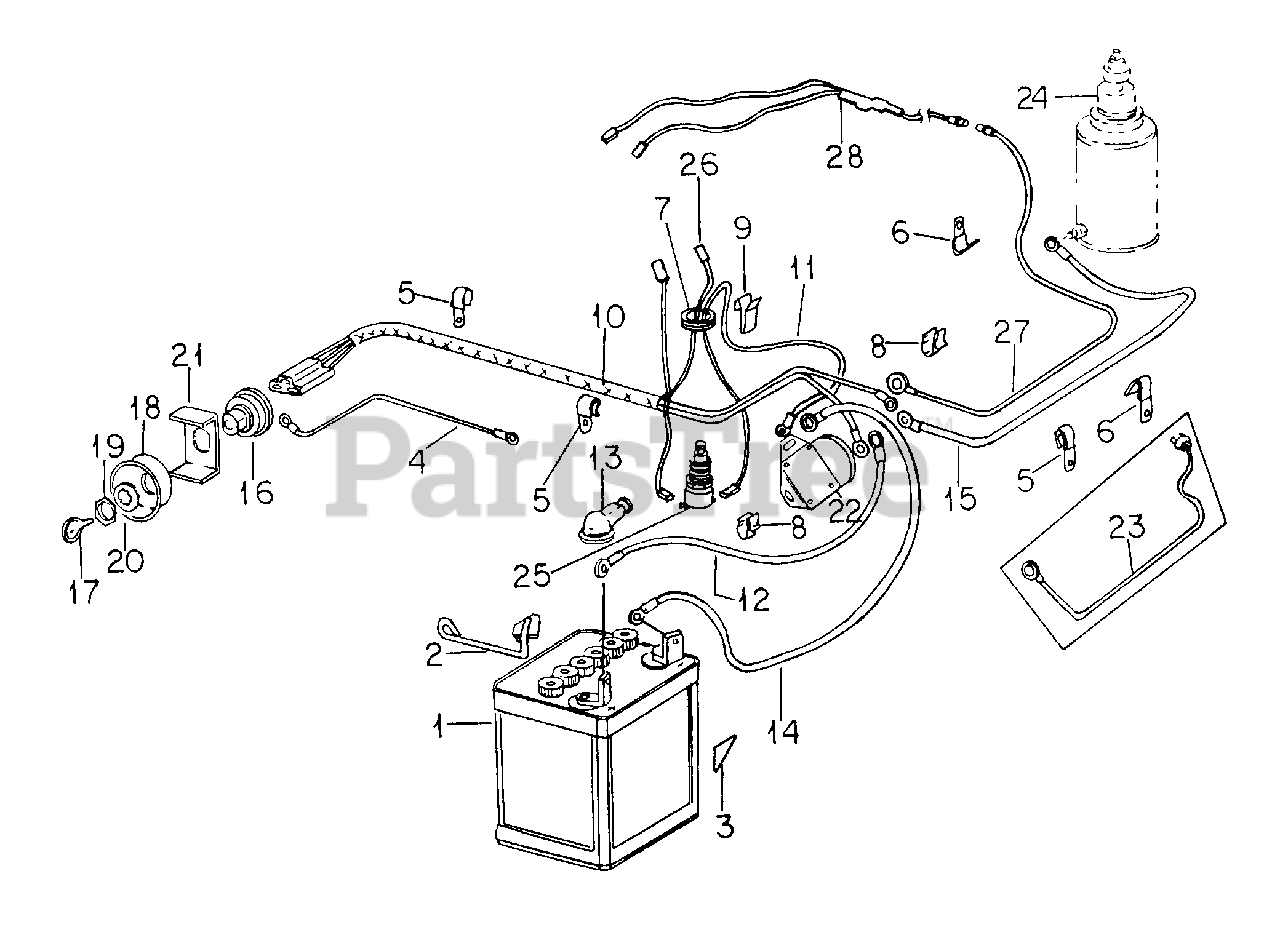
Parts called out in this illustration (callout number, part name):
1	BATTERY, LOW-MAINTENANCE -12 VOLT-
2	CLAMP ASSY, BATTERY
3	PAD, BATTERY
4	CABLE ASSY, SWITCH TO GROUND
6	CLIP, CABLE
8	CLIP. SPEED
9	CLIP, CABLE SPEED
10	HARNESS, CABLE
11	CABLE, PTO SWITCH TD MAGNETIC SWITCH
12	CABLE, BATTERY POSITIVE
13	INSULATOR, BATTERY CABLE
14	CABLE, BATTERY GROUND
15	CABLE, SWITCH TO STARTER
16	SWITCH MAGNETO IGNITION AND STARTING
17	KEY, IGNITION SWITCH
18	SOCKET, IGNITION SWITCH
19	NUT, MAGNETO IGNITION KEY MOUNTING
20	WASHER, MAGNETO IGNITION KEY MOUNTING
21	RETAINER, IGNITION SWITCH
22	SWITCH, MAGNETIC
23	CABLE, SWITCH TO FUSE -16 IN. LONG-
24	STARTING MOTOR
25	SWITCH ASSY, NEUTRAL STARTING
26	CABLE, SWITCH TO TRANSMISSION
27	CABLE, SWITCH TO ALTERNATOR
28	DIODE ASSY, TRI CIRCUIT
